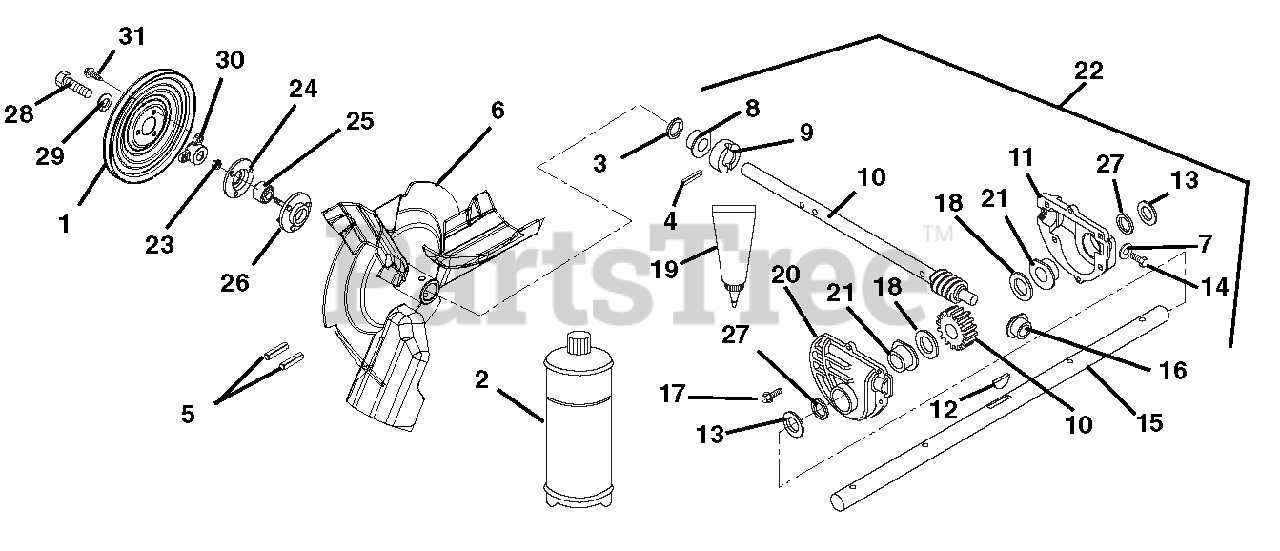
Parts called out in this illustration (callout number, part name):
1	PULLEY,SPIN FORM SINGLE GROOVE
2	ARIENS 16 OZ.BOTTLE OF L2 LUBE
3	SEAL-OIL.748X1.378X.276 RBR OD
4	@PIN-GRV .188X1.25 TP E ALLOY
5	PIN-ROLL .250X1.75
6	IMPELLER, COMPACT 12" 3-BLADE
7	WSHR-FIBER .437X.656X.032
8	BSHG-FLG .750X1.000X.750X1.250
9	THRUST COLLAR, .75" ID
10	SHAFT AND WORM GEAR ASSEMBLY
11	GEARCASE CASTING, MACHINED LH
12	KEY-WDRF .19X.63 HRD #61
13	@WSHR-FL-STL.812X1.50X.135YWZC
14	SCR-TAP .38-16X.75 ROLOK YZ WX
15	SHAFT, RAKE - 24" (.750 DIA)
15	SHAFT, RAKE - 26" (.750 DIA)
16	BSHG-FLG .502X1X.750
17	@SCR-TAP .25-20X1.00 HWH TR YZ
18	WSHR-FL-STL.755X1.375X.062YWZC
19	LOCTITE 518 GASKET--6ML TUBE
20	GEARCASE CASTING, MACHINED RH
21	BSHG-FLG .753X1.127X.500X1.501
22	GEARCASE, 24" ALUM, SMALL CD
22	GEAR CASE ASSEMBLY - 26" ALUM.
23	@NUT-LK-CTR .25-20 YWZC
24	BEARING FLANGE
25	BRG-BALL .750X1.750X.50
26	BEARING FLANGE
27	SEAL-OIL .750X1.375X.250
28	BLT-HEX .31-24X.75 YWZC GR5
29	WSHR-LK .312X.097 HVY YWZC
30	PULLEY HUB, BOLT-ON D-BORE .75
31	@SCR-TAP .31-18X.50 HWH TR YWZ
